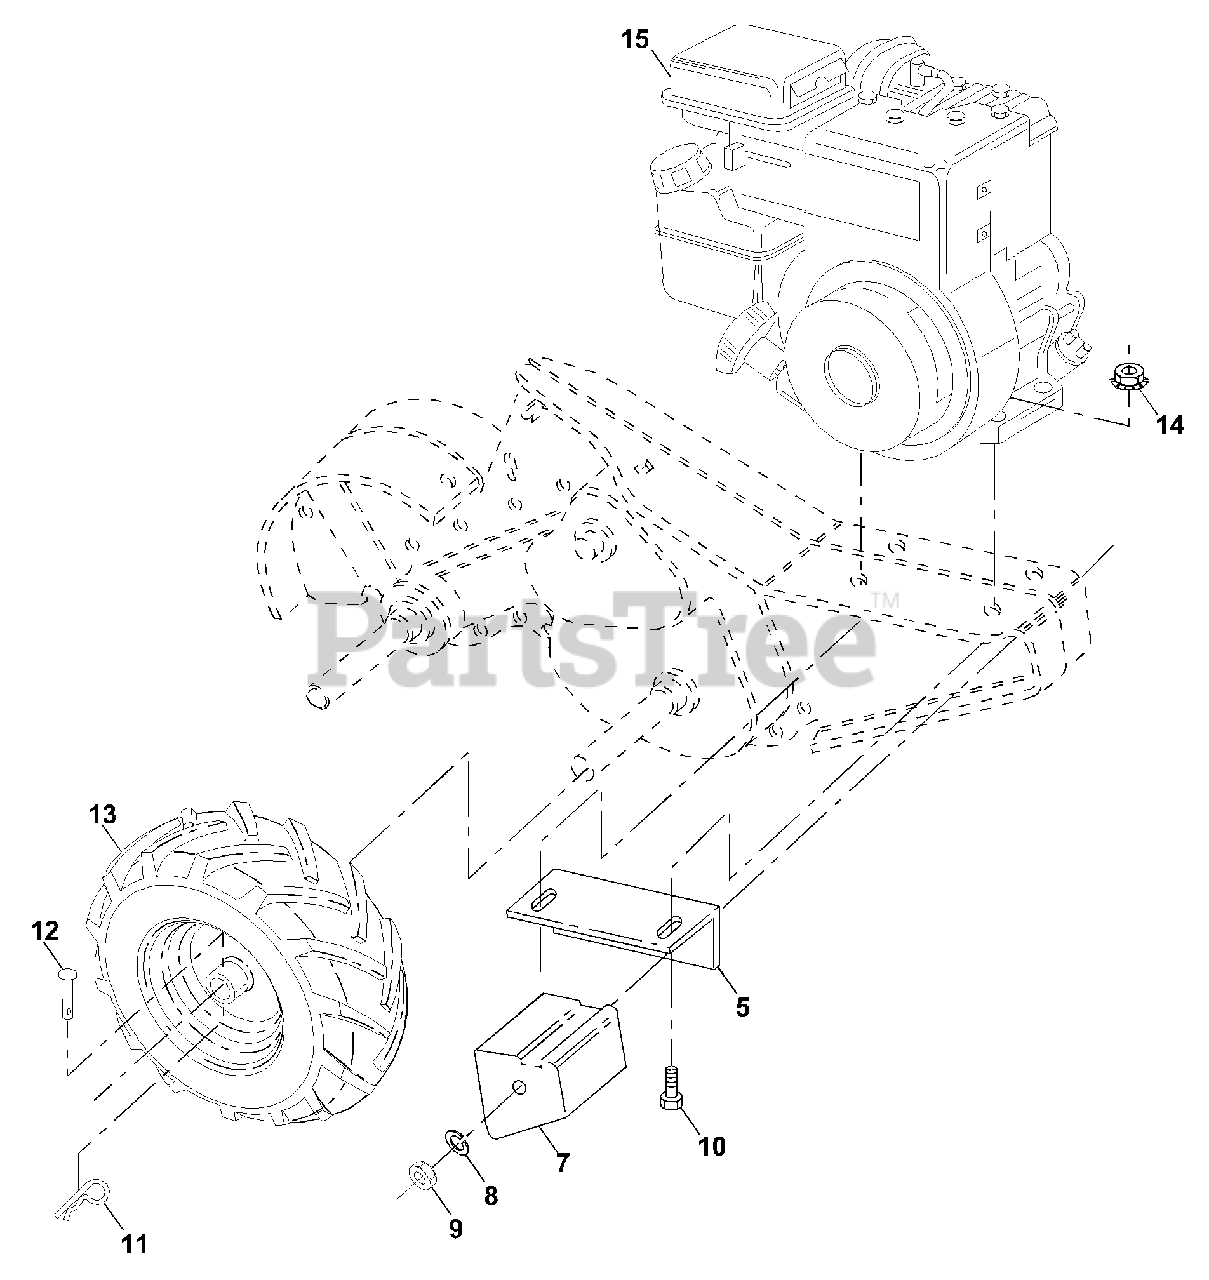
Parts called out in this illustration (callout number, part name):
5	Bracket, Reinforcement
7	Counter Weight, R.H.
8	Washer, Lock 3/8
9	Nut, Hex 3/8-16
10	Bolt, Hex 5/16-18 x 1-1/2
11	Clip, Hairpin
12	Rivet, Drilled
13	Tire
13	Tire Valve
14	Nut, Keps 5/16-18
